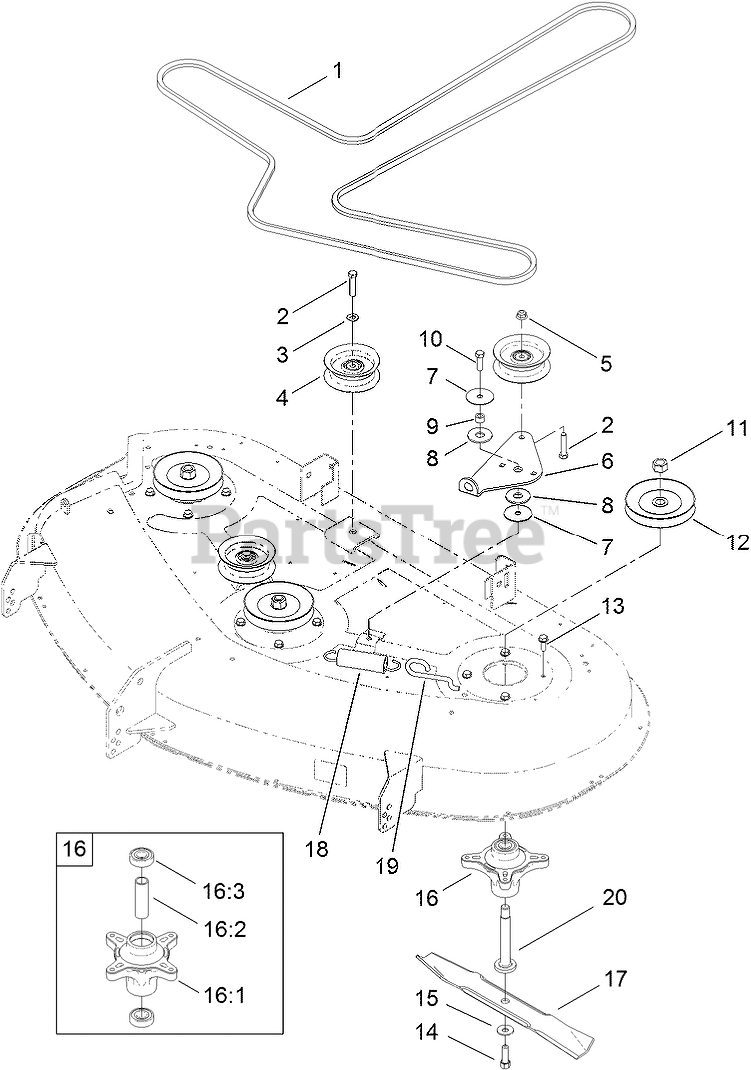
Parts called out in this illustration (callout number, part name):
1	V-BELT
2	SCREW-HH
3	WASHER-FLAT
4	PULLEY-IDLER, FLAT
5	NUT-HF, NI
6	ARM-IDLER
7	WASHER
8	WASHER-FRICTION, COMPOSITE
9	SPACER
10	SCREW-HH
11	NUT-HEX
12	PULLEY
13	SCREW-TAPTITE
14	SCREW-HH
15	WASHER-BELLEVILLE
16	SPINDLE ASM
16:1	SPINDLE
16:2	SPACER
16:3	BEARING-BALL
17	BLADE-MULCH, 17.50 INCH
18	SPRING-EXTENSION
19	HOOK-RETURN, SPRING
20	SHAFT-SPINDLE
